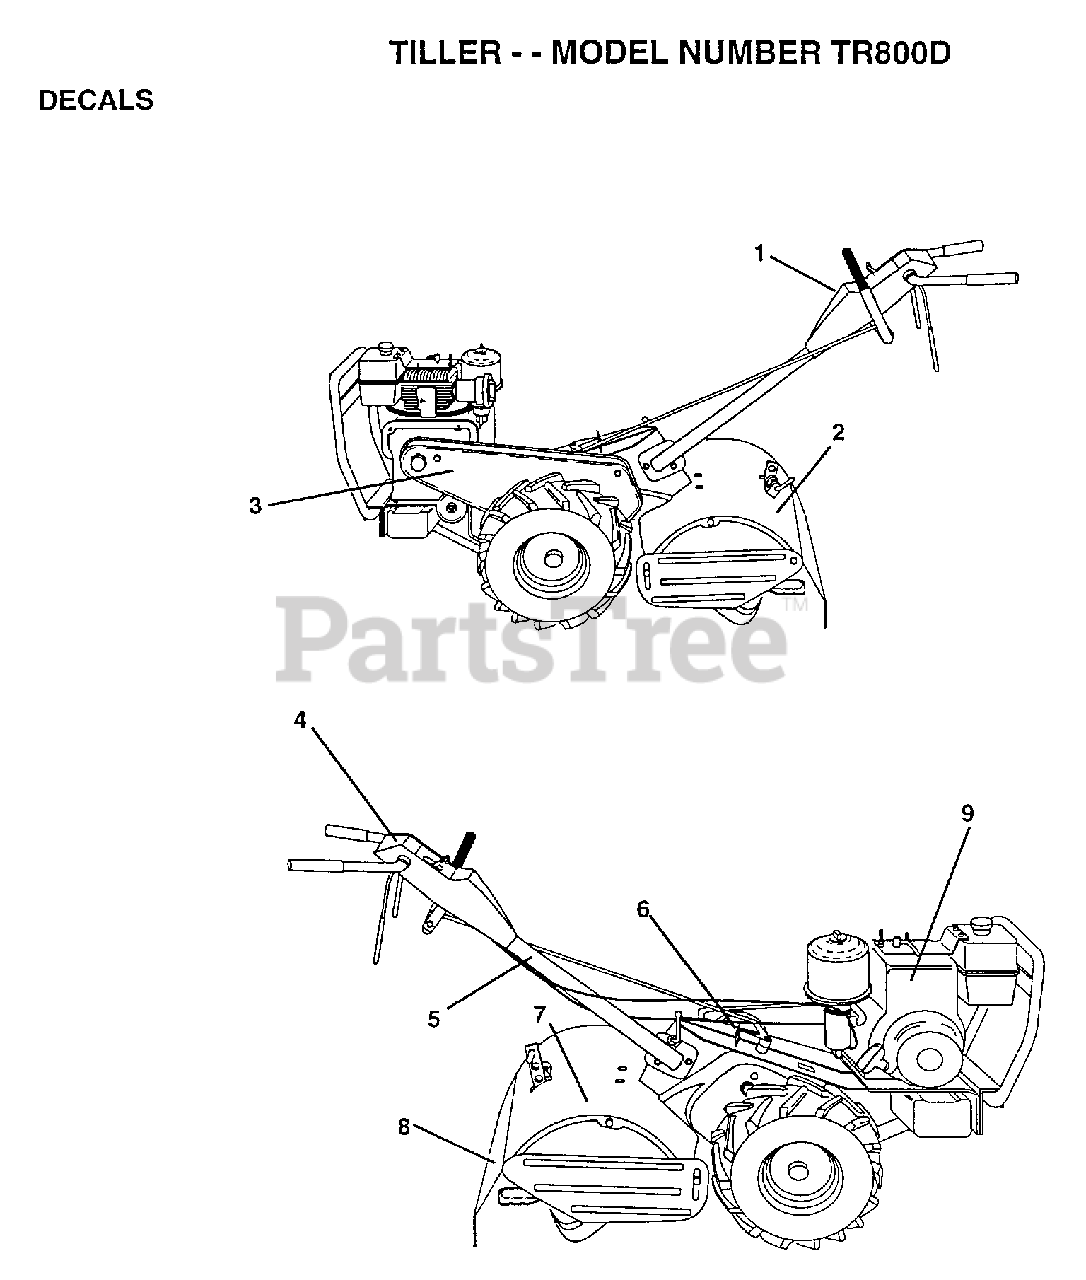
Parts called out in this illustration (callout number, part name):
1	DECAL.PNL.CONTROL
2	DECAL.SHLD.TINE
3	DECAL.GRD.BELT
4	DECAL.INST.PNL.CT
5	DECAL TI
6	DECAL.SHIFT.IND.
8	DECAL TI
9	DECAL, BRIGGS & STRATTON
